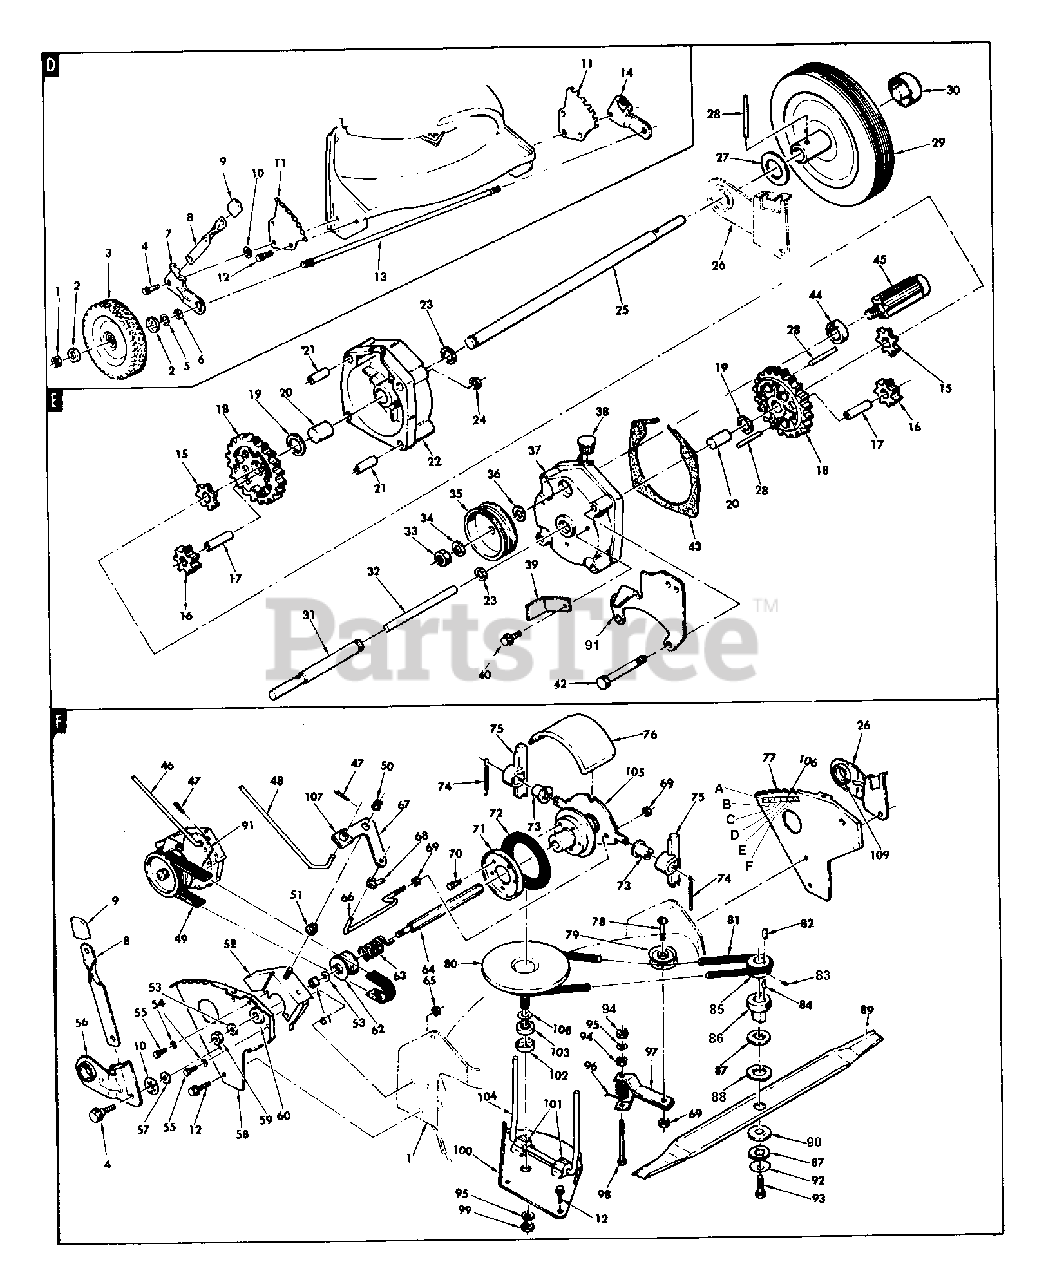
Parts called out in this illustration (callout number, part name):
1	7/16-20 Jam Lock Nut
2	Hub Cap, Front
3	Front Wheel, 7 x 1:50
4	5/16 Shoulder Screw
5	Spring Washer
7	Wheel Arm, Front R. H
8	Height Latch
9	Grip
10	Push Nut
11	Front Bracket
12	5/16-18 x 5/8 SEMS
13	Front Axle
14	Wheel Arm, Front L. H.
15	Differential Gear, 12T, 12P
16	12 Tooth, 12 Pitch Gear
17	Shaft
18	46 Tooth, 12 Pitch Gear
19	Thrust Washer
20	Bearing
21	Roll Pin
22	Outboard Housing
23	Seal
24	1/4-28 Hex Lock Nut
25	Long Axle
26	Wheel Arm, Rear L.H.
27	3/4 Washer
28	Roll Pin, 3/16 x 1 5/8
29	Rear Wheel
30	Plastic Hub Cap
31	Short Axle
32	Pin
33	7/16-20 Hex Nut
34	Spring Washer
35	Polly "V" Pulley
36	Spring Washer
37	Inboard Housing
38	Plug
39	Belt Guide
40	1/4-20 x 5/8 HWST
42	1/4-28 x 3 1/4 HHCS
43	Gasket
44	Ball Bearing
45	Input Gear Assembly
46	Release Rod
47	1/8 x 3/4 Cotter Pin
48	Shift Linkage
49	200J6 Polly "V" Belt
50	5/16-24 Flanged Lock Nut
51	Friction Washer
52	Bell Crank Str.
53	Belleville Washer
54	1/4 SAE WASHER
55	1/4-20 x 5/8 SEMS
56	Wheel Arm, Rear R. H.
57	5/16 SAE Washer
58	Rear Bracket, R. H.
59	3/8-24 Hex Lock Nut
60	Ball Bearing
61	Flex Bushing
62	Polly "V" Pulley
63	Rev KO Spring
64	Hex Shaft
65	5/16-18 Hex Jam Nut
66	Clutch Rod
67	Bell Crank
68	Cluth Rod Clip
69	1/4-28 Hex Lock Nut
70	SCREW, #10-24 x 1/2" Hex Washer Self-Tap (Torx)
71	Tire Plate
72	RING, Driven (Rubber Disc)
73	Pivot Bearing
74	Clutch Spring
75	Slide Block
76	Cover
77	Rear Bracket, L. H.
78	1/4-28 x 1 1/2 FHMS
79	Idler Pulley
80	Drive Disc Assembly
81	3L 255 "V" Belt
82	Hi Pro Key
83	1/4-20 x 5/16 SKT. Head Set Screw
84	KEY, (#6) 5/32 x 5/8" Woodruff
85	Engine Pulley
86	Shock Clutch
87	Clutch Washer
88	Fibre Washer
89	Cutter Bar
90	Fibre Washer
91	Transmission Release Brkt.
92	Clutch Washer
93	3/8-24 x 2 GR. 5 Cap Screw
94	3/8-24 Hex Lock Nut
95	3/8 Internal Tooth Lock Washer
96	Idler Spring
97	Idler Arm
98	3/8-24 x 3 HHCS
99	3/8-24 Hex Nut
100	Disc Plate
101	Pillow Block
102	Bearing Shield
103	Felt Seal
104	Shift Fork
105	Driven Disc Assembly
107	Wear Block
108	3/8 SAE Washer
109	Bearing
